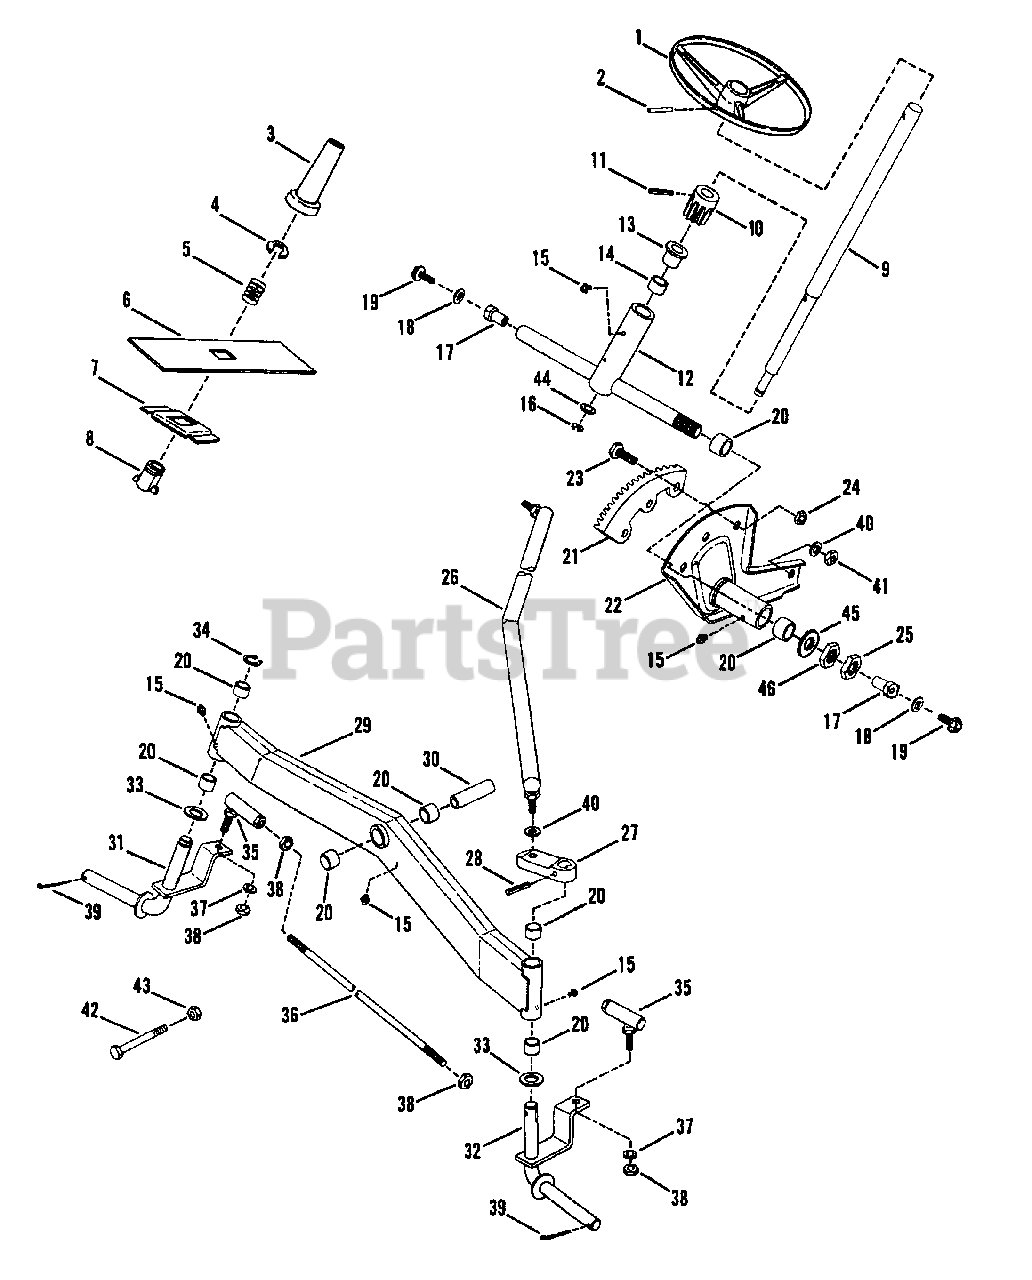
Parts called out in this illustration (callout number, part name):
1	STEERING WHEEL
2	ROLL-PIN, 1/4" x 2-1/4"
3	ACTUATOR, Steering Lock
4	RING, 13/16" External Retaining
5	SPRING, Actuator
6	COVER, Slide
7	RISER, Steering Lock
8	BUSHING, Steering Lock
9	SHAFT, Steering
10	PINION, Steering
11	ROLL-PIN, 3/16 x 1-1/2"
12	ASSEMBLY, Bearing Support
13	BEARING, Flange
14	BUSHING
15	LUBE FITTING, Straight (press-fit for .187 dia. Hole)
16	SNAP-RING, 5/16
17	PIVOT
18	WASHER, 5/16 Internal Tooth Lock
19	SCREW, 5/16-18 x 3/4" Hex Washer Self-Tap
20	BEARING
21	QUADRANT, Steering
22	ASSEMBLY, Sector
23	SCREW, 1/4-20 x 5/8" Hex Head Cap, Grade 5
24	NUT, 1/4-20 Hex Center Lock, Grade B or 5
25	NUT, 3/4-16 Hex Jam
26	DRAG-LINK
27	ARM, Steering
28	ROLL-PIN, 1/4 x 1-1/4"
29	ASSEMBLY, Front Axle
30	JOURNAL, Axle
31	KING-PIN, Right Side
32	KING-PIN, Left Side
33	WASHER, Thrust
34	RING, 3/4" External Retaining
35	BALL JOINT, 3/8-24 Thread
36	TIE-ROD
37	WASHER, 3/8" Split Lock
38	NUT, 3/8-24 Hex, Grade 2
39	COTTER-PIN, 5/32 x 1"
40	WASHER, 1/2 Split Lock
41	NUT, 1/2-20 Hex, Grade 2
42	SCREW, 1/2-20 x 4" Hex Head Cap, Grade 5
43	NUT, 1/2-20 Hex Thin Lock
44	WASHER, 3/8" Flat
45	WASHER, 3/4" I.D. Flat
46	NUT, 3/4-16 Hex
